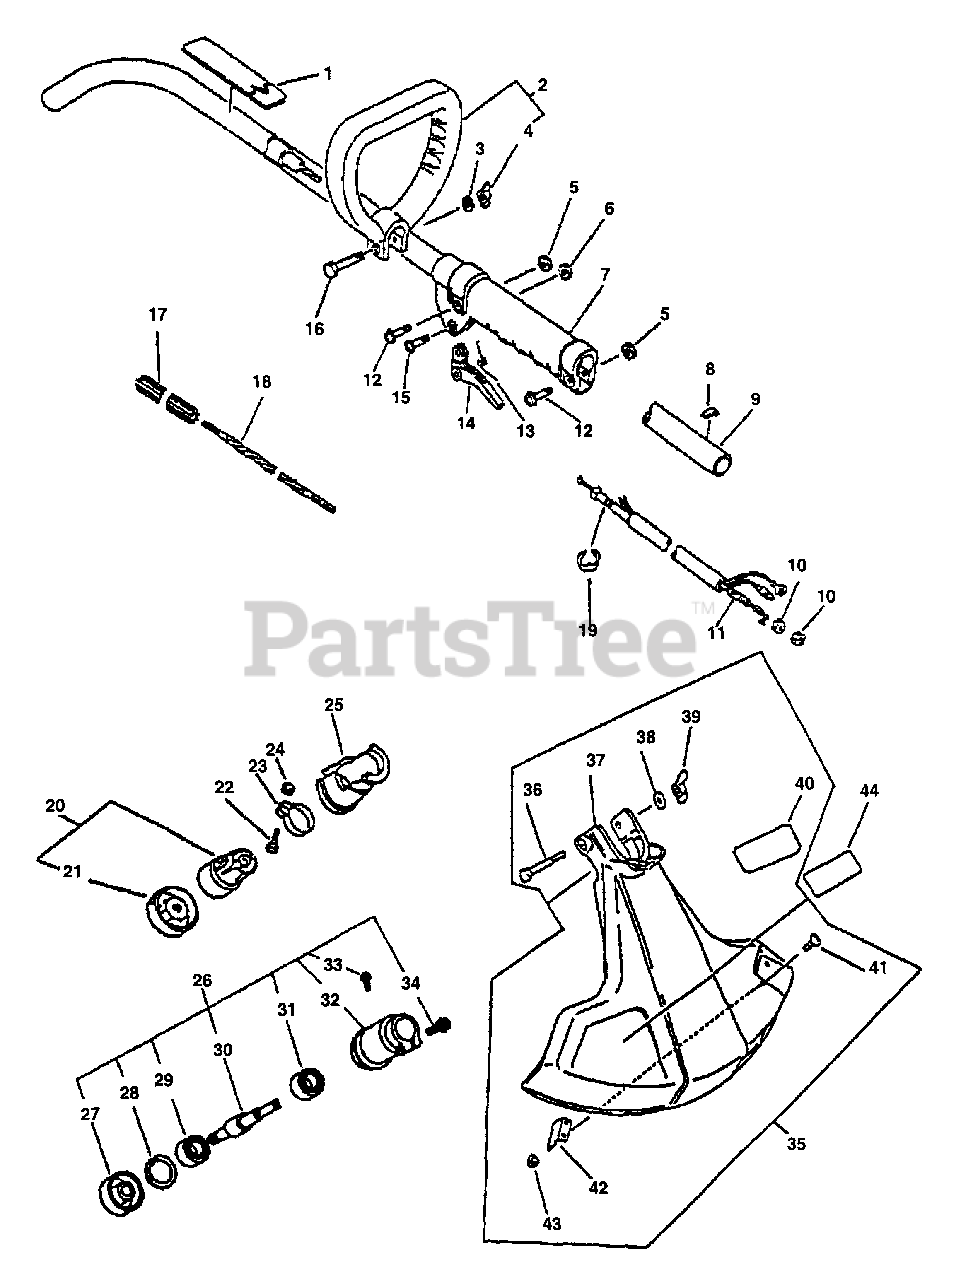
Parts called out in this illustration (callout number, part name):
1	LABEL, CAUTION
2	HANDLE ASSY
3	WINGNUT - 6
3	NUT - 1/4-20
4	WASHER 6.5×11.5×0.8
4	WASHER, 1/4"
5	NUT M5
6	NUT, LOCK M5
8	LABEL - ALIGNMENT
9	MAIN PIPE ASSY
11	CABLE, THROTTLE
12	SCREW 5×25
13	SPRING, THROTTLE
14	TRIGGER, THROTTLE
16	BOLT - 6×40
16	BOLT 1/4"-20×1-1/2"
17	LINER - FLEXIBLE
18	DRIVESHAFT - FLEXIBLE
19	RING, RETAINING - 5
19	E-RING 4
20	GEAR CASE ASSY
21	PLATE, ADAPTER - UPPER
22	BOLT M5×10
23	BAND
24	NUT M5
25	BRACKET, BEARING CASE
26	GEAR CASE ASSY
27	PLATE, ADAPTER - UPPER
28	E-RING 30
29	BEARING, BALL 6200
30	GEAR, SHAFT
31	BEARING, BALL 6200
32	CASE, GEAR
33	SCREW 4×10
34	BOLT - 5×25
35	DEBRIS SHIELD KIT
36	BOLT - 6×50
36	BOLT 1/4"-20×2"
37	SHIELD
38	WASHER 6.5×11.5×0.8
38	WASHER, 1/4"
39	WINGNUT - 6
39	NUT - 1/4-20
40	LABEL, CAUTION
41	SCREW 5×16
42	CUTTER, LINE
43	NUT M5
44	LABEL, ECHO
